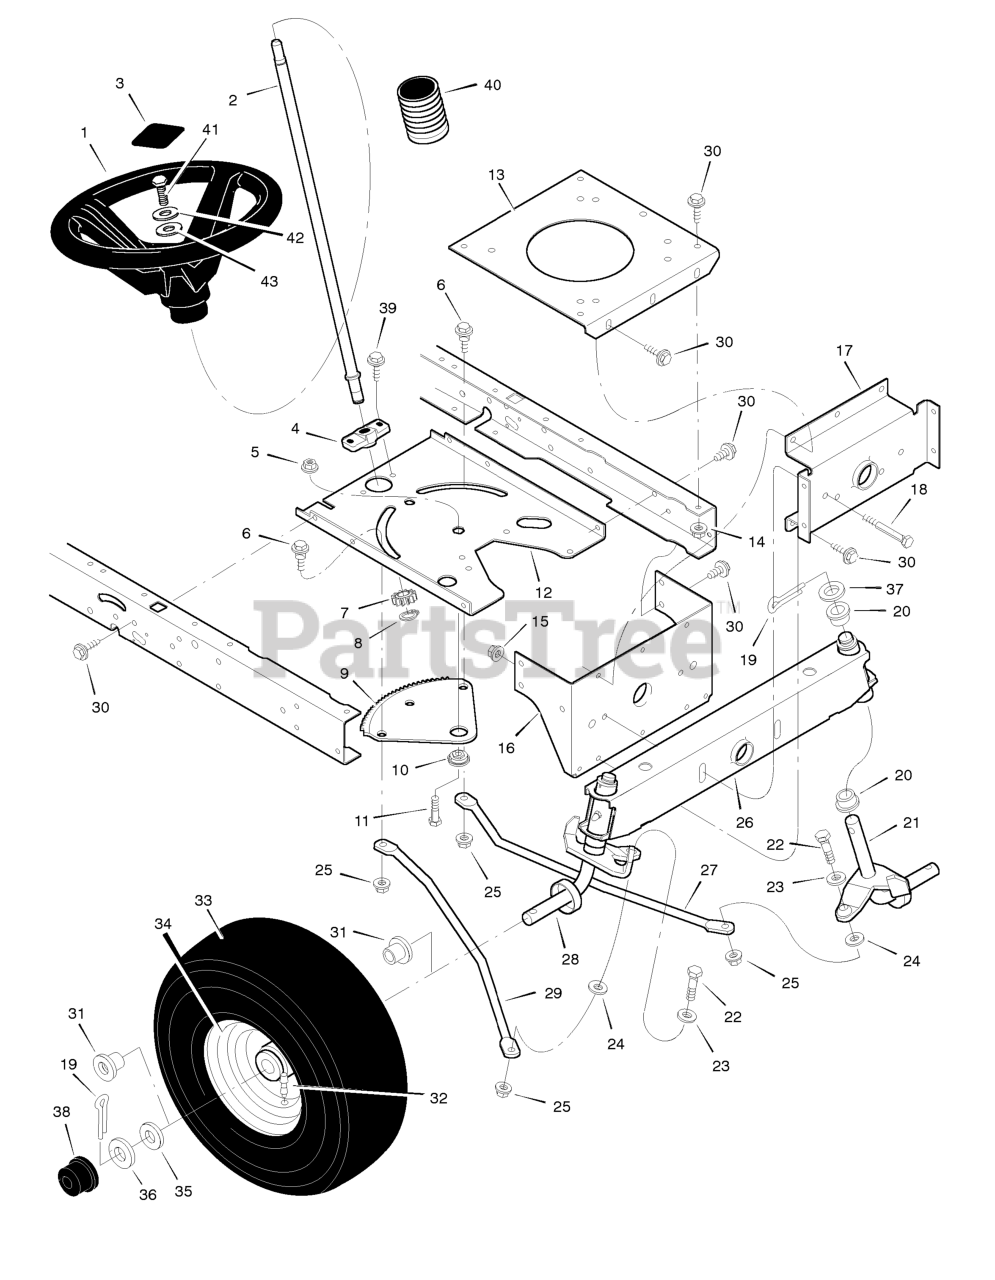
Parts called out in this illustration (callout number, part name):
1	Wheel, Steering
2	Post, Steering
3	Insert, Steering Wheel
4	Bearing
5	Nut, Flange
6	Bolt, Shoulder
7	Gear, Pinion
8	Ring, Snap
9	Gear, Sector
10	Bearing
11	CAPSCREW, Hex Head, 5/16-18 x 1
12	Plate, Steering
13	Plate, Engine
14	Nut, Flange
15	Nut, Flange
16	Bracket, Hanger
17	Axle, Hanger
19	Pin, Cotter
20	Bearing
21	Spindle Assembly, Left
22	Bolt
23	Washer
25	Nut, Flange
26	Axle Assembly
27	Drag Link, Left
28	Spindle Assembly, Right
29	Drag Link, Right
31	Bearing, Wheel
32	Stem, Valve
34	Wheel and Tire Assembly
38	Hub Cap
40	Bellows
42	Lockwasher
